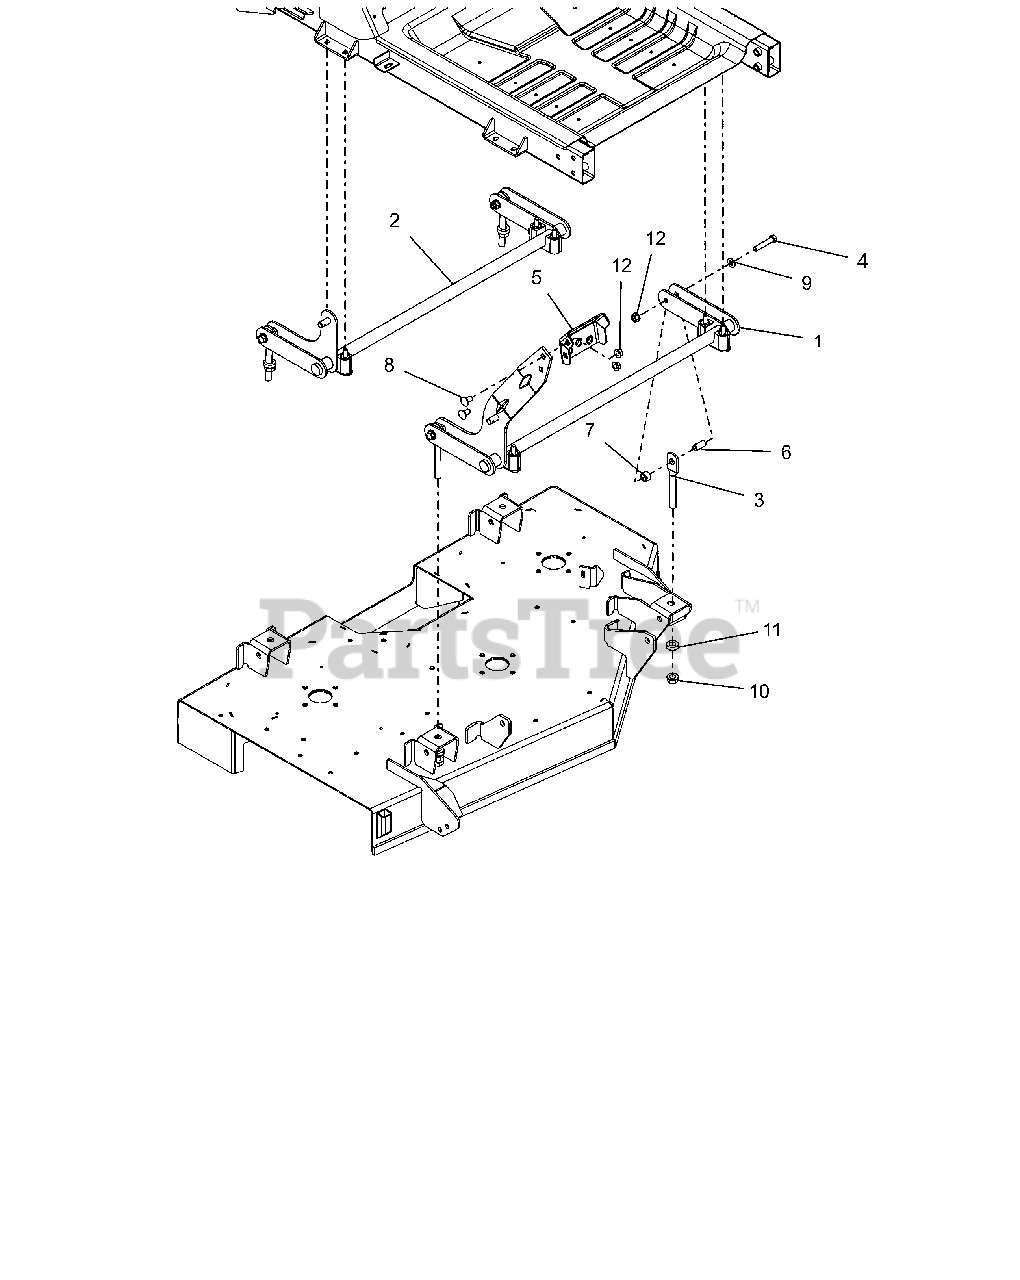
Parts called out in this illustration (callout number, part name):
1	WLDMT, FRONT DECK LIFT PIVOT
2	WLDMT, REAR DECK PIVOT
3	LINK, DECK (HOLE-LONG)
4	BLT, HEX .38-16X2.00 G8 ZCC
5	PEDAL, DECK LIFT (BOLT ON)
6	BSHG-SLV .385X.500X1.045
7	BSHG-SLV .510X.751X.475
8	BLT,RHSN .38-16X.75 G5 BFP
9	WSHR,FLT .406X.812X.065 ZCC
10	NUT-LK-CTR-FLG .500-13 GG ZCC
11	WSHR, RUBBER
12	NUT-LK-CTR-FLG .375-16 GF ZCC
